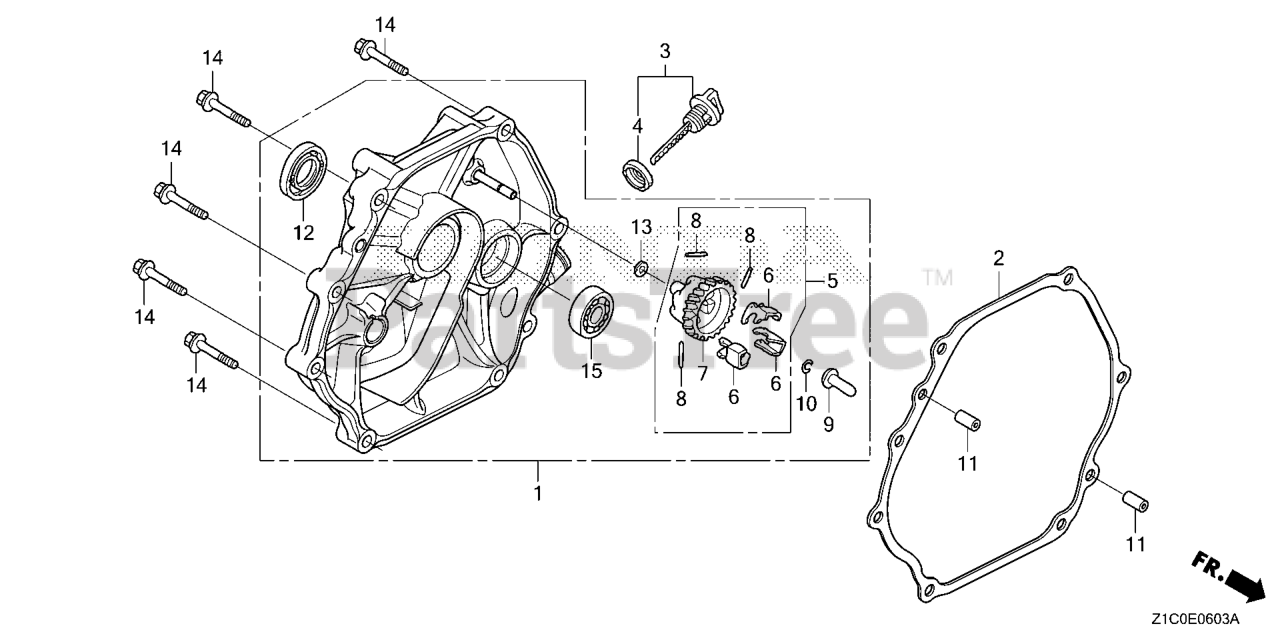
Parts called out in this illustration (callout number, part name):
1	COVER ASSY., CRANKCASE
1	COVER ASSY,CRANK
2	GASKET, CRANKCASE COVER
3	CAP ASSY., OIL FILLER
4	GASKET, OIL FILLER CAP
5	GOVERNOR ASSY.
6	WEIGHT, GOVERNOR
7	HOLDER, GOVERNOR WEIGHT
8	PIN, GOVERNOR WEIGHT
9	SLIDER, GOVERNOR
10	CLIP, GOVERNOR HOLDER
11	PIN, DOWEL (8X12)
12	OIL SEAL (35X52X8) (NOK)
13	WASHER, PLAIN (6MM)
14	BOLT, FLANGE (8X40) Use up to Engine SN 1003236.
15	BEARING, RADIAL BALL (6202)
